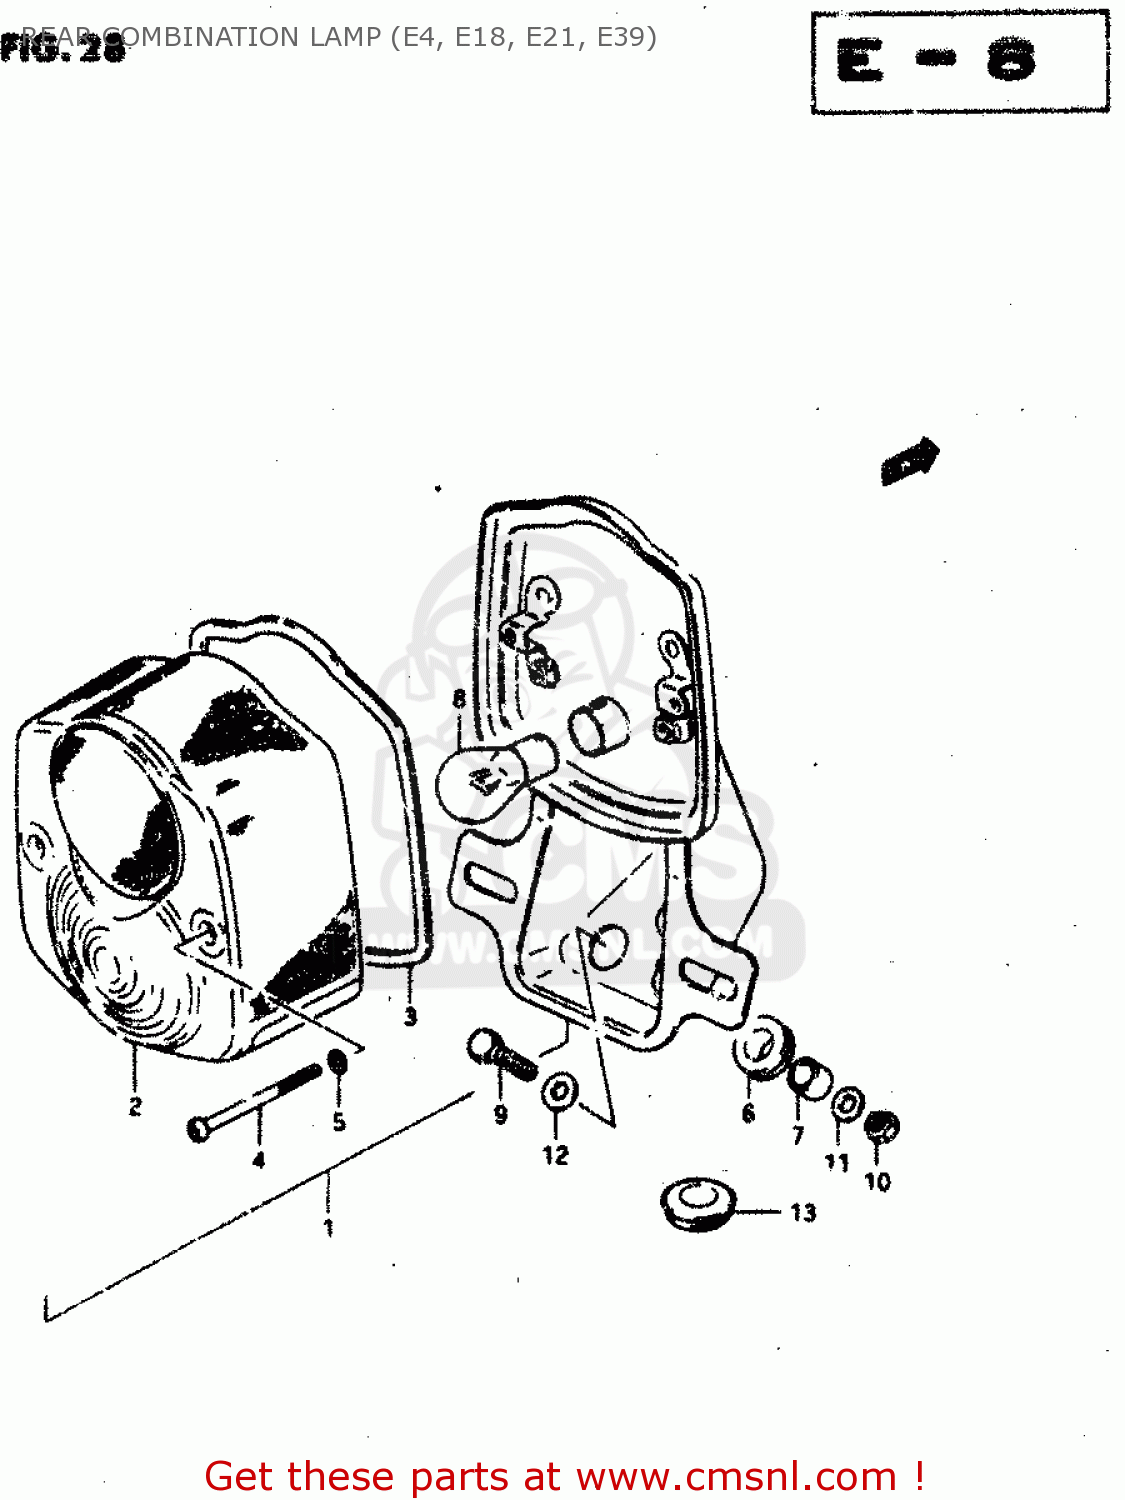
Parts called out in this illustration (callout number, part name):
1	LAMP ASSY, TAIL
2	LENS,RR COMBI
3	GASKET (NAS)
4	SCREW
5	GASKET (NAS)
6	CUSHION
7	SPACER,REAR COMBINATION LAMP
8	BULB (6V,21/5W)
9	BOLT, UPPER
10	NUT
11	WASHER
12	WASHER (6.5X20X1.2)
13	GROMMET
